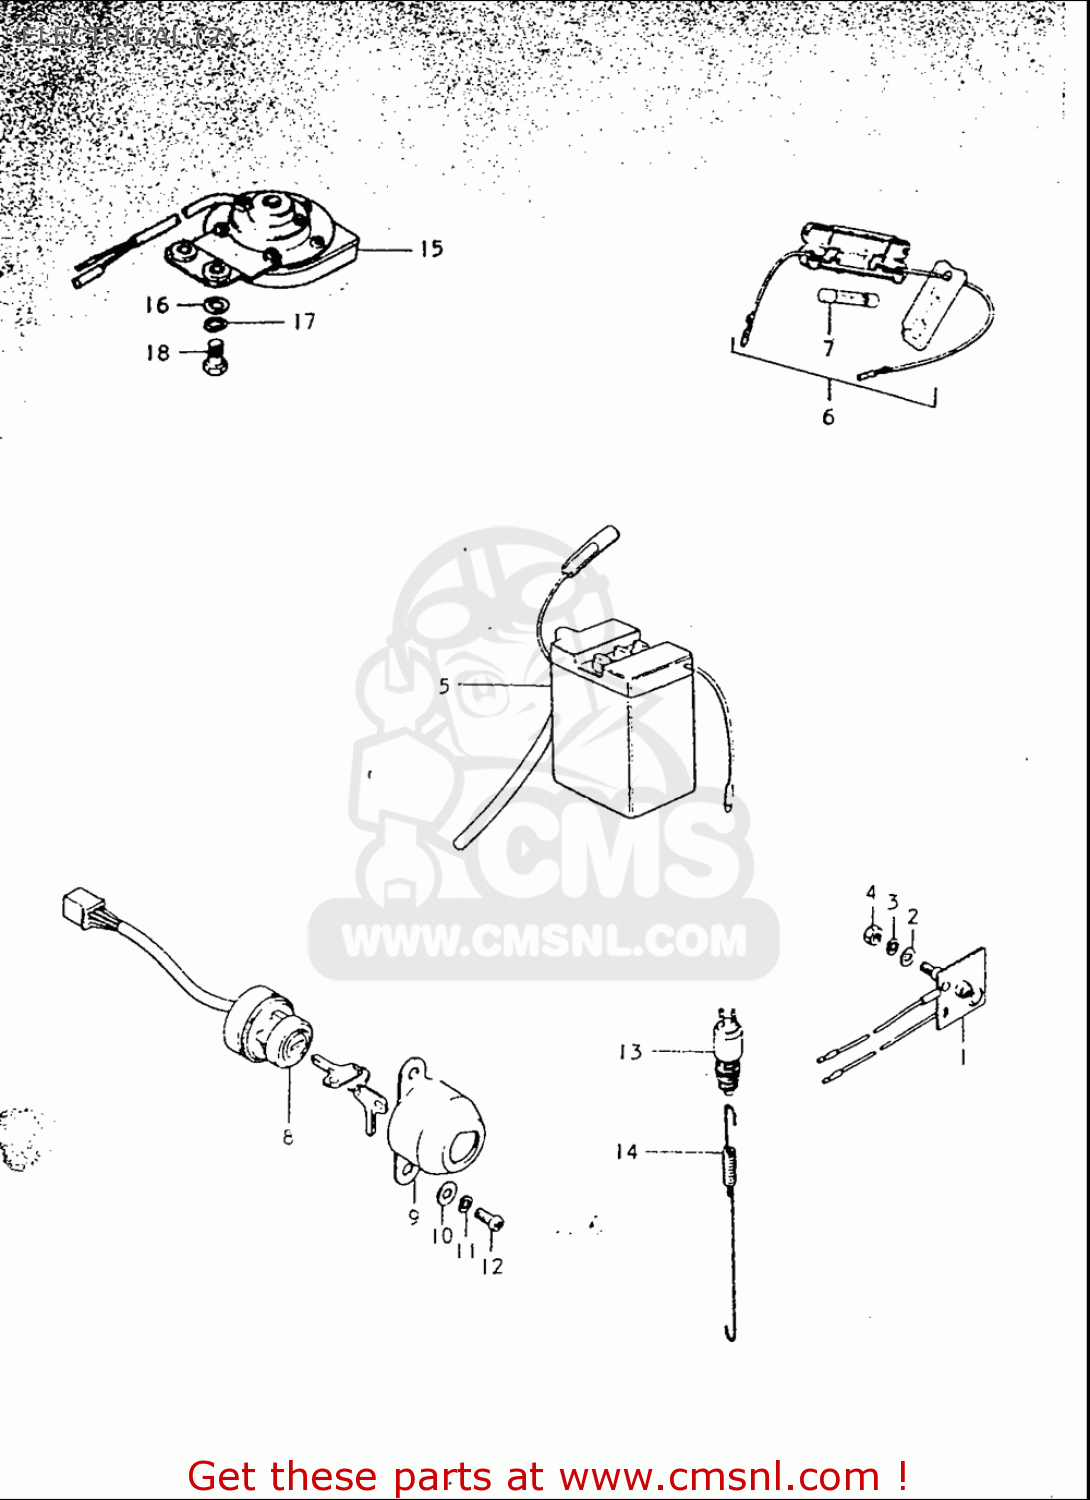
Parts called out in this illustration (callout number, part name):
2	WASHER
3	WASHER,LOCK
4	NUT
5	BATTERY ASSEMBLY (6V)
6	CASE ASSY,FUSE
7	FUSE(15A)
10	WASHER
11	WASHER,LOCK
12	SCREW
13	SWITCH ASSY,BRAKE LAMP
15	HORN ASSEMBLY
16	WASHER
17	WASHER,LOCK
